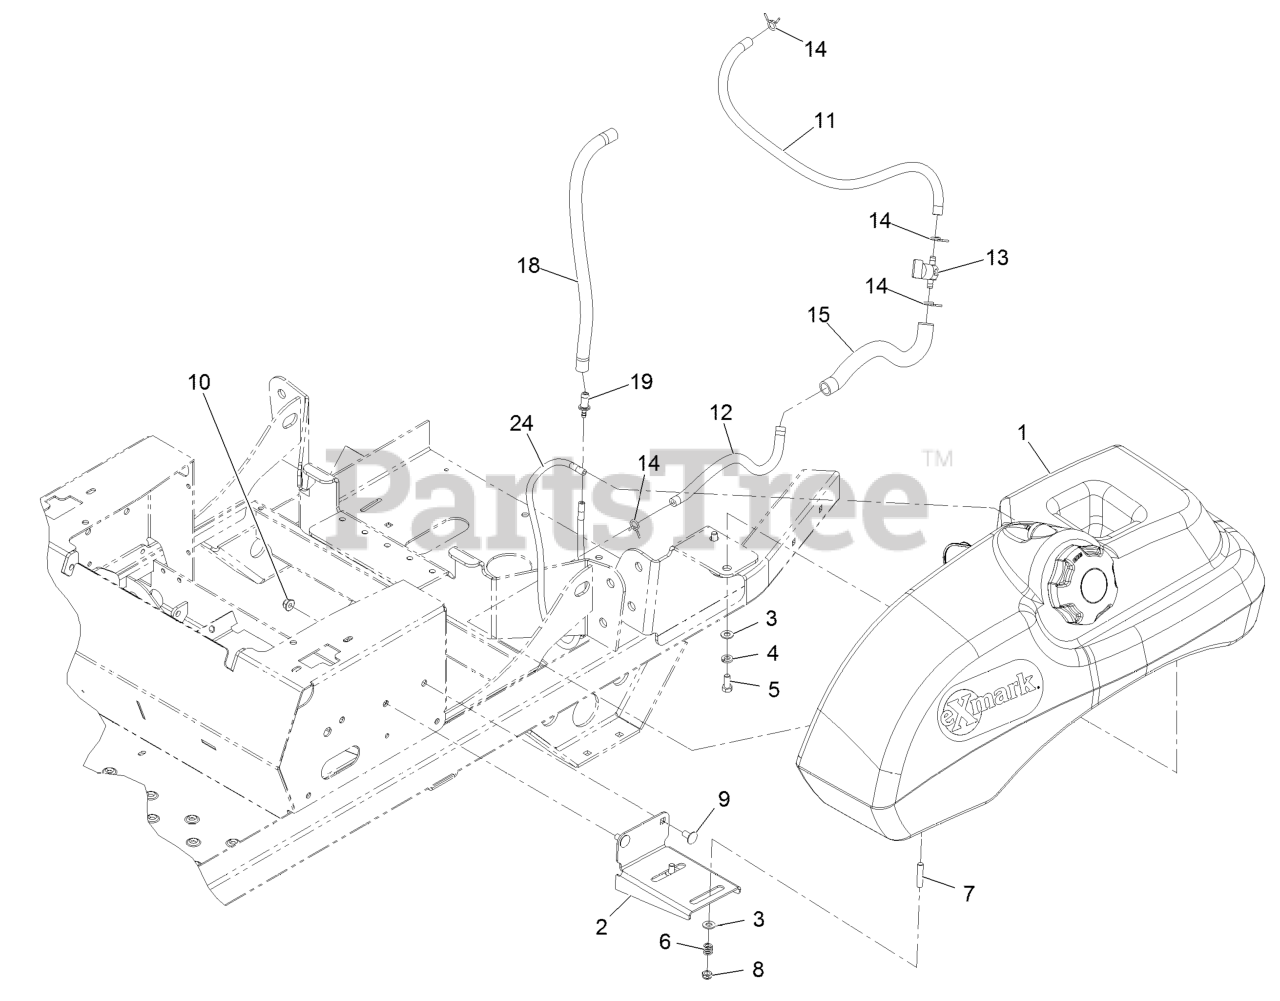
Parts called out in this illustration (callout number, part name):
1	ASM-FUEL TANK
2	BRACKET-TANK AND FENDER
3	WASHER-PLAIN
4	WASHER-LOCK
5	SCREW-HH
6	SPRING-TANK, FUEL
7	STUD
8	NUT-LOCK, NI
9	SCREW-CARR
10	NUT-HF, NI
11	HOSE-FUEL
12	HOSE-FUEL
13	VALVE-FUEL
15	CONDUIT-FUEL LINE
18	HOSE-FUEL
19	FITTING-ORIFICE, STRAIGHT
24	HOSE,EMISSIONS
